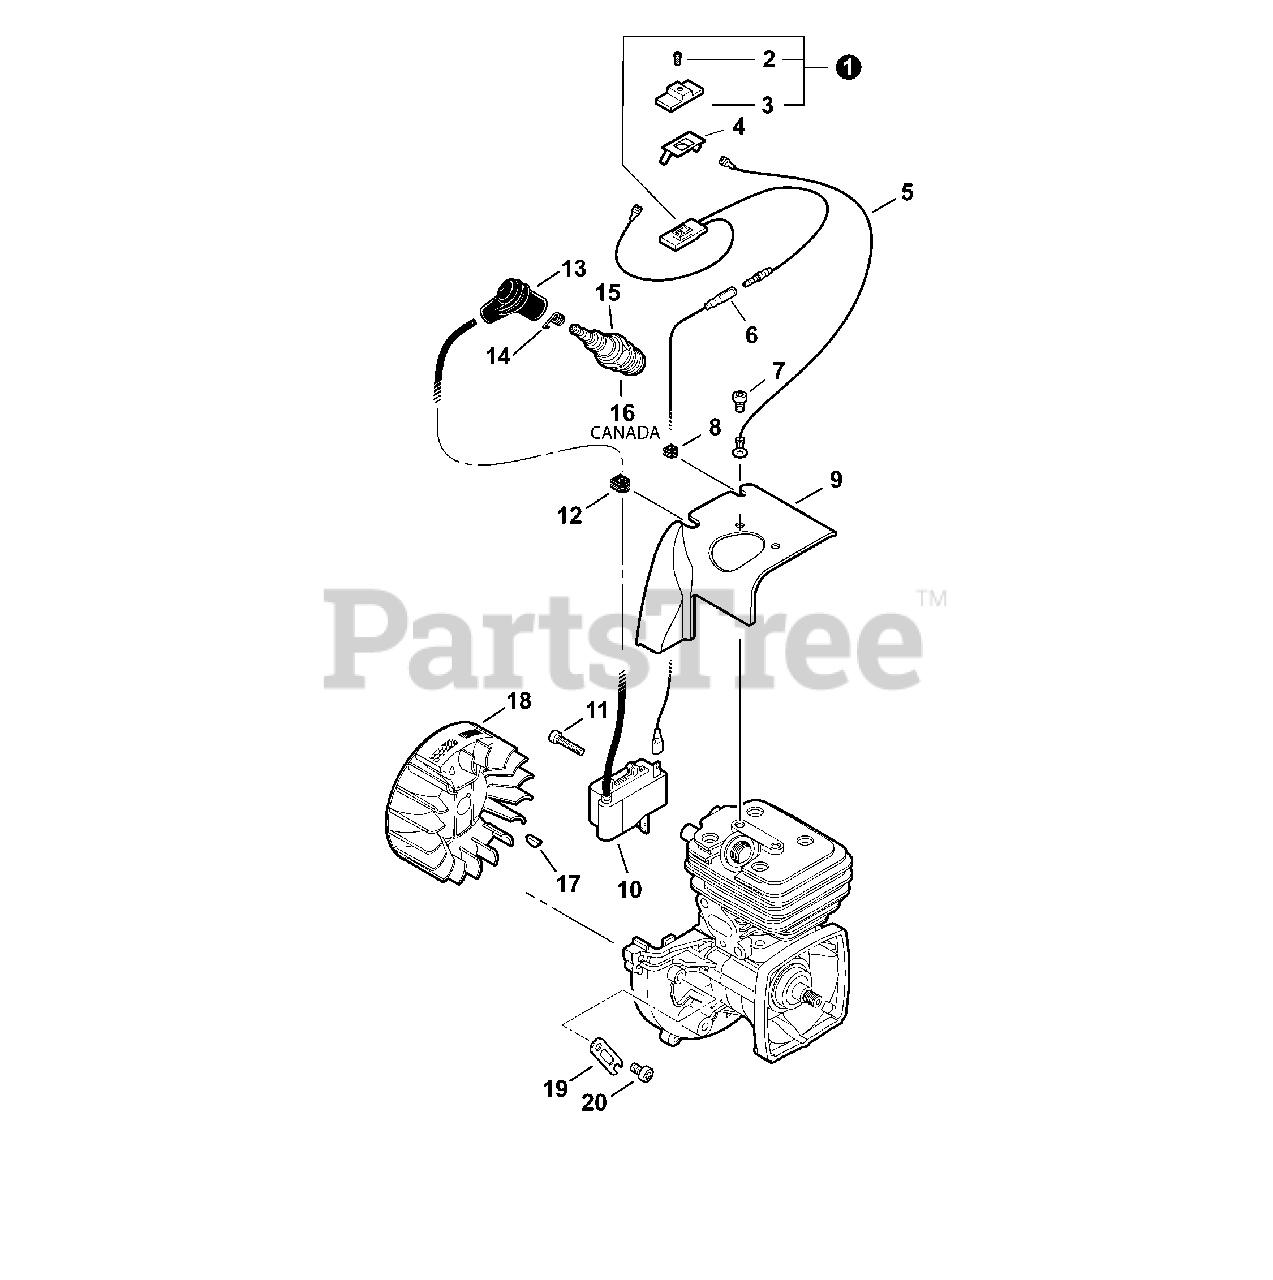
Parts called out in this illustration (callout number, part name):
1	SWITCH ASSY, ON-OFF
2	SCREW 3×10
3	KNOB, SWITCH
4	TERMINAL, LEAD
5	LEAD L= 210 MM
6	LEAD L= 85 MM
7	BOLT, TORX 5×8
9	SHIELD, CYLINDER
10	COIL, IGNITION
11	BOLT, TORX 4×20
13	CAP, SPARK PLUG
14	TERMINAL, SPARK PLUG
15	SPARK PLUG - BPM8Y
16	SPARK PLUG - BPMR8Y
17	KEY, WOODRUFF
18	FLYWHEEL
19	PLATE, EYE
20	BOLT, TORX 5×8
